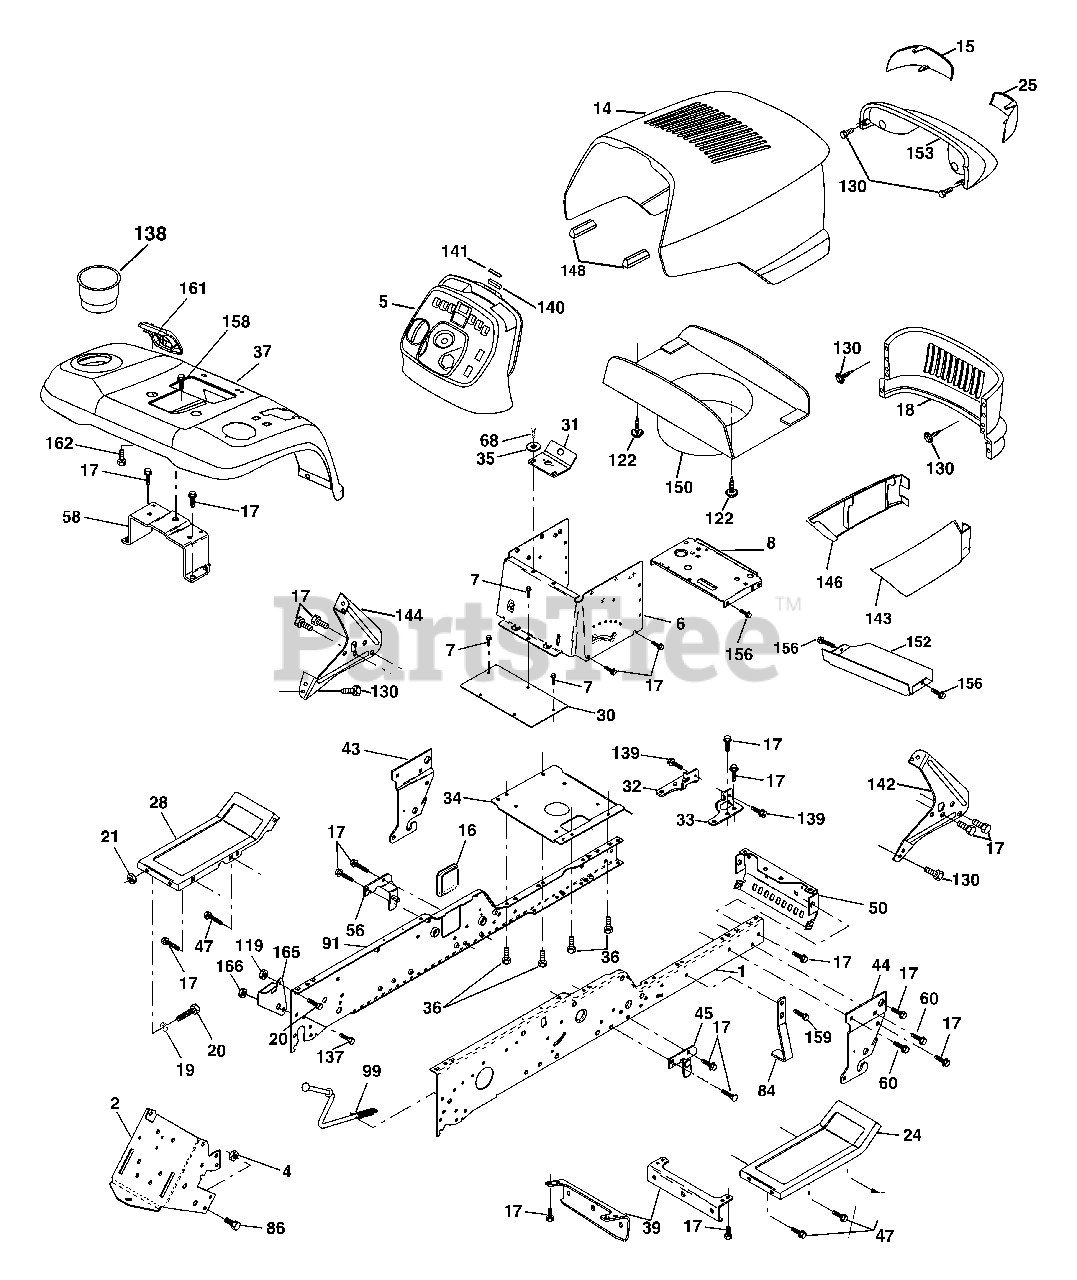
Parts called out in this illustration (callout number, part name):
1	Rail, Frame RH
2	Drawbar, Gt
4	Nut, Lock Hex 7/16 Unc
5	Dash, Plastic
6	Dash, 1PCS, Lower
7	Screw, Thd Cut 1/4-20 x 1/2
8	Support, Battery
14	Hood Asm., Pnt
15	Lens LH
16	Cover, Access
17	Screw, 3/8-16 x 3/4
18	Grille
19	Washer 13/32 x 13/16 x 12 Ga.
20	Bolt, Fin Hex 3/8-16 x 1
21	Nut, Crownlock 3/8-16
24	Footrest, RH
25	Lens RH
28	Footrest, LH
31	Bracket Supt 1-pc Vgt Steering
32	Bracket, Frame Pivot Lh
33	Bracket, Frame Pivot Rh
34	Plate Asm Engine Chassis
35	Washer 11/32 x 11/16 x 16 Ga.
36	Screw 5/16-18 x 3/4
37	Fender, Pnt.
39	Bracket, Axle Front
43	Bracket, Spnsn Front Lh
44	Bracket, Spnsn Front Rh
45	Bracket Asm., Susp Chassis Rh
47	Screw Thdrol 3/8-16 x 1/2
50	Bracket, Chassis Front
56	Bracket Asm., Susp Chassis Lh
58	Bracket Asm., Fender
60	Screw 3/8-16 x 1-1/4
68	Screw, 5/16-18 x 1/2
84	Stop Over Center
86	Bolt, Fin Hex 7/16-14 Unc x 1
91	Rail, Frame Lh
99	Rod Asm. Bypass
119	Nut Crownlock 3/8-16 Unc
122	Screw Hex WSHD 8-18 x 7/8
130	Screw Hw Hd Hi-Lo #13-16 x 3/4
137	Bolt Fin Hex 7/16-14 x 1 Gr. 5
138	Cupholder
139	Bolt Shoulder 5/16-18
140	Magnet Stealth
141	Striker Plate
142	Bracket Dash Stealth RH
143	Skirt Grille RH
144	Bracket Dash Stealth LH
146	Skirt Grille LH
148	Extrusion Bumper
150	Duct Heat Hood
152	Shield, Browning
153	Light Box Asm w/Lens
156	Screw 5/16-18 x 3/4
158	Screw 3/8-16 x 1/2
159	Screw Hex Wsh Thdrol 3/8-16 x 3/4
161	Consol Fuel Window
162	Screw Hex Wsh Hi-Lo 1/4-1/2 Unc
165	Bracket Support Fuel Tank
166	Nut Crownlock 7/16-14
